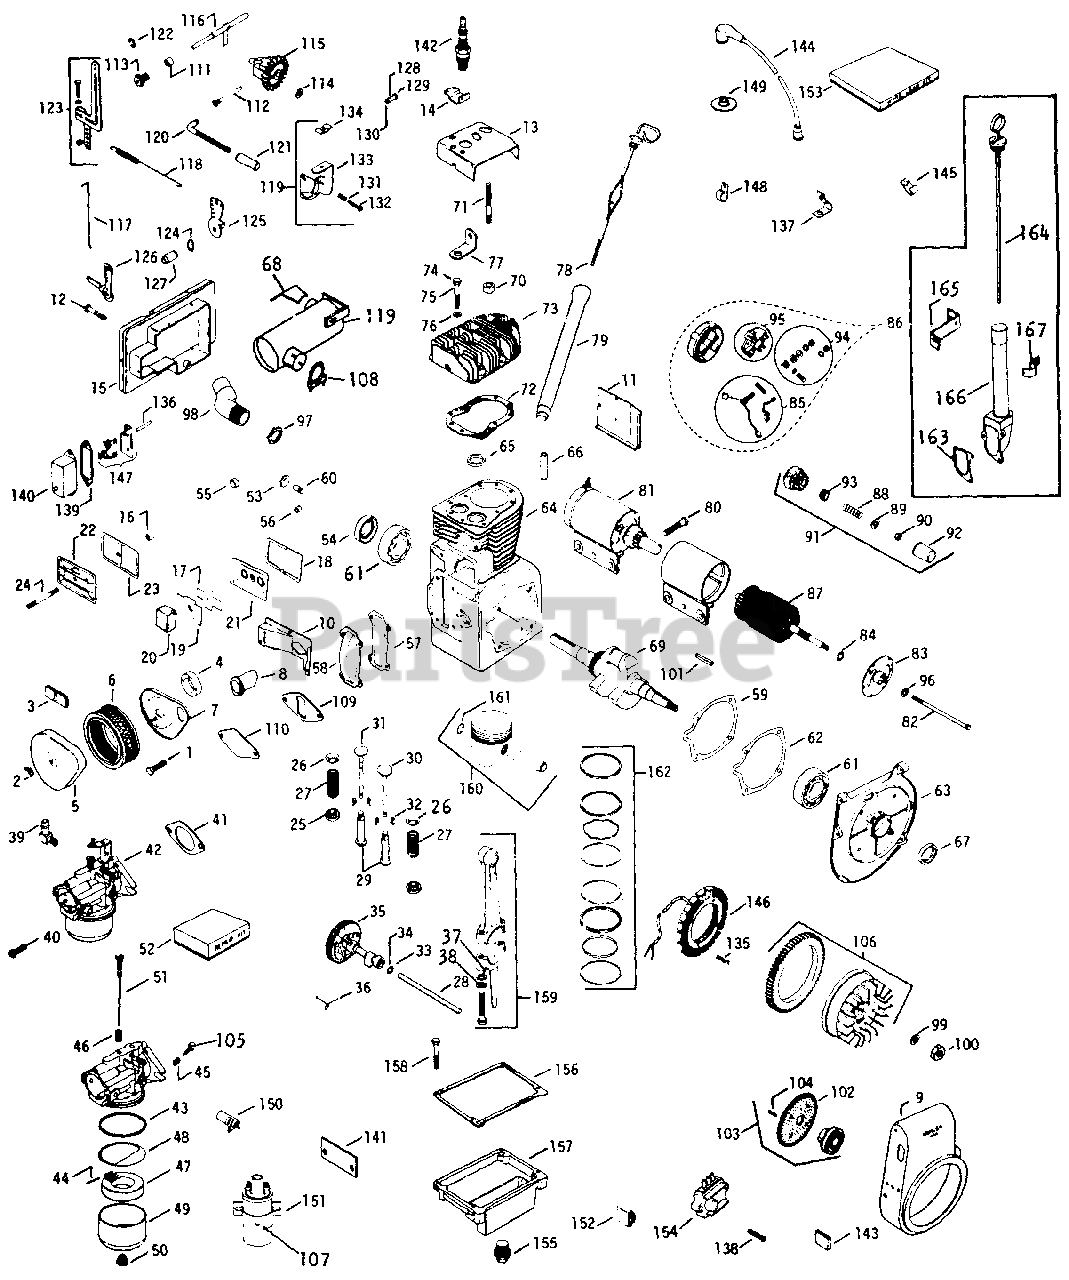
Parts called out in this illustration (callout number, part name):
1	Screw, 10-32 X 1/2 Znd Hex Hd Self Tap
2	Nut, Wing
4	Gasket, Air Cleaner
5	Cover, Air Cleaner
6	Element, Air Cleaner
7	Base, Air Cleaner
8	Tube, Air Cleaner
9	Housing, Blower
10	Baffle, Side
11	Baffle, Cylinder
12	Screw, 1/4-20 X 3/4 Hex Hd
13	Baffle, Head
14	Bracket, Lifting
16	Seal, Breather
17	Reed, Breather
18	Gasket, Cover
19	Baffle, Breather
20	Filter, Breather
21	Plate, Breather
22	Cover, Breather
23	Gasket, Valve Cover
24	Stud, Valve Cover
25	Rotator, Valve
26	Retainer, Valve Spring
27	Spring, Valve
28	Pin, Camshaft
29	Tappet Assy
30	Valve, Intake
31	Valve, Exhaust
32	Keeper, Valve Spring
33	Shim, Camshaft, .005
34	Shim, Camshaft, .010
35	Camshaft Assy
36	Spring, Camshaft Actuating
37	Washer, Connecting Rod
38	Washer, 3/8 Heavy Lock
39	Elbow, Hose Connector
40	Screw, 5/16-18 X 1 Hex Hd Sems
41	Gasket, Carburetor
42	Carburetor Assy
43	Gasket, Fuel Bowl
44	Pin, Hinge
45	Spring, Idle Adjusting Screw
46	Spring, High Speed Needle
47	Float & Lever Assy
48	Gasket, Bowl Baffle
49	Bowl, Fuel
50	Screw w/Gasket, Fuel Bowl
51	Needle, High Speed
52	Kit, Carburetor Repair
53	Plug, 1-1/8 Expansion
54	Seal, Rear Oil
55	Plug, 1/2 Cup
56	Bearing, Crankcase Needle
57	Gasket, Cam Cover
58	Cover, Cam
59	Gasket, Bearing Plate, .010
60	Shaft, Governor
61	Bearing, Crankcase Ball
62	Gasket, Bearing Plate
63	Plate, Bearing
64	Block, Cylinder
65	Insert, Seat Valve
66	Guide, Valve
67	Seal, Front Oil
68	Deflector, Exhaust
70	Spacer
71	Stud, Cylinder Head
72	Gasket, Cylinder Head
73	Head, Cylinder
74	Screw, 3/8-16 X 1-1/2 Znd Hex Hd Cap Type 8
75	Screw, 3/8-16 X 1-3/4 Znd Hex Hd Cap Type 8
76	Washer, Head
77	Bracket, Baffle Mounting
78	Dipstick w/Shoulder Mount
79	Tube, Oil Fill w/Shoulder Mount
80	Bolt, Shoulder
81	Starter Assy
83	Cap Assy, Drive End
84	Washer, Armature Thrust
85	Kit, Starter Brush
86	Cap Assy, Commutator End
88	Spring, Anti-Drift
89	Spacer, Stop Gear
90	Nut, 5/16-24 Hex Lock
91	Kit, Starter Drive w/Shim
92	Cover, Dust
93	Spacer
94	Kit, Hardware
95	Kit, Brush Holder
96	Washer, 1/4 Znd Reg Lock
97	Nut, Lock
98	Elbow, Exhaust
100	Nut, 5/8-18 Znd Hex Lock
101	Key, 3/16 X 1-3/8 Sq Parallel
102	Screen, Grass
103	Cup Assy, Flywheel Drive
104	Pin, Flywheel Drive Cup
105	Screw, Idle Adjusting
106	Flywheel Assy
107	Clamp, Ignition Coil
108	Clamp Assy, Muffler
109	Gasket, Pump Cover
110	Cover, Pad
111	Spacer
112	Pin, Governor Stop
113	Bushing, Governor
114	Washer, Thrust
115	Gear, Governor
116	Shaft, Governor
117	Linkage, Choke
118	Spring, Governor
119	Muffler Assy
120	Rod, Ball Joint
121	Body, Ball Joint
122	Retainer, Throttle Rod
123	Lever, Governor
124	Washer, Tension
125	Lever, Throttle Control
126	Lever, Choke Control
128	Clamp, Swivel Wire
129	Washer, 9/32 X 5/8 X .062 Znd
130	Screw, 1/4-20 X 1-1/4 Hex Hd Sems
131	Spring, Adjusting
132	Screw, Throttle
133	Bracket, Control
134	Clamp, Wire
135	Screw, 10-24 X 3/8 Fil Hd Mach
136	Rod, Breaker
137	Clip, High Tension
138	Screw, 10-24 X 1 Znd Pan Hd Mach
139	Gasket, Breaker Cover
140	Cover, Breaker
141	Bar, Coil Bracket Back Plate
142	Plug, Spark (Champion)
143	Connector
144	Kit, Hi-Tension Lead
145	Clip, Terminal
146	Kit, Stator
147	Breaker & Bracket Assy
148	Clip, Cable
149	Grommet, Spark Plug
150	Condenser, Ignition Coil
151	Coil, Ignition
153	Kit, Wire Lead Cable
154	Regulator Assy
155	Plug, Drain
156	Gasket, Oil Pan Base
157	Base, Oil Pan
158	Screw w/Lock Washer, 3/8-16 X 1-1/2 Znd Hex Hd
159	Rod Assy, Connecting, Std
160	Piston Assy, Std
161	Retainer, Piston Pin
162	Ring Set, Piston, Std
163	Gasket, Oil Fill Tube
164	Dipstick w/o Shoulder Mount
165	Bracket, Dipstick Tube
166	Tube Assy, Oil Fill w/o Shoulder Mount
167	Clamp, Conduit
